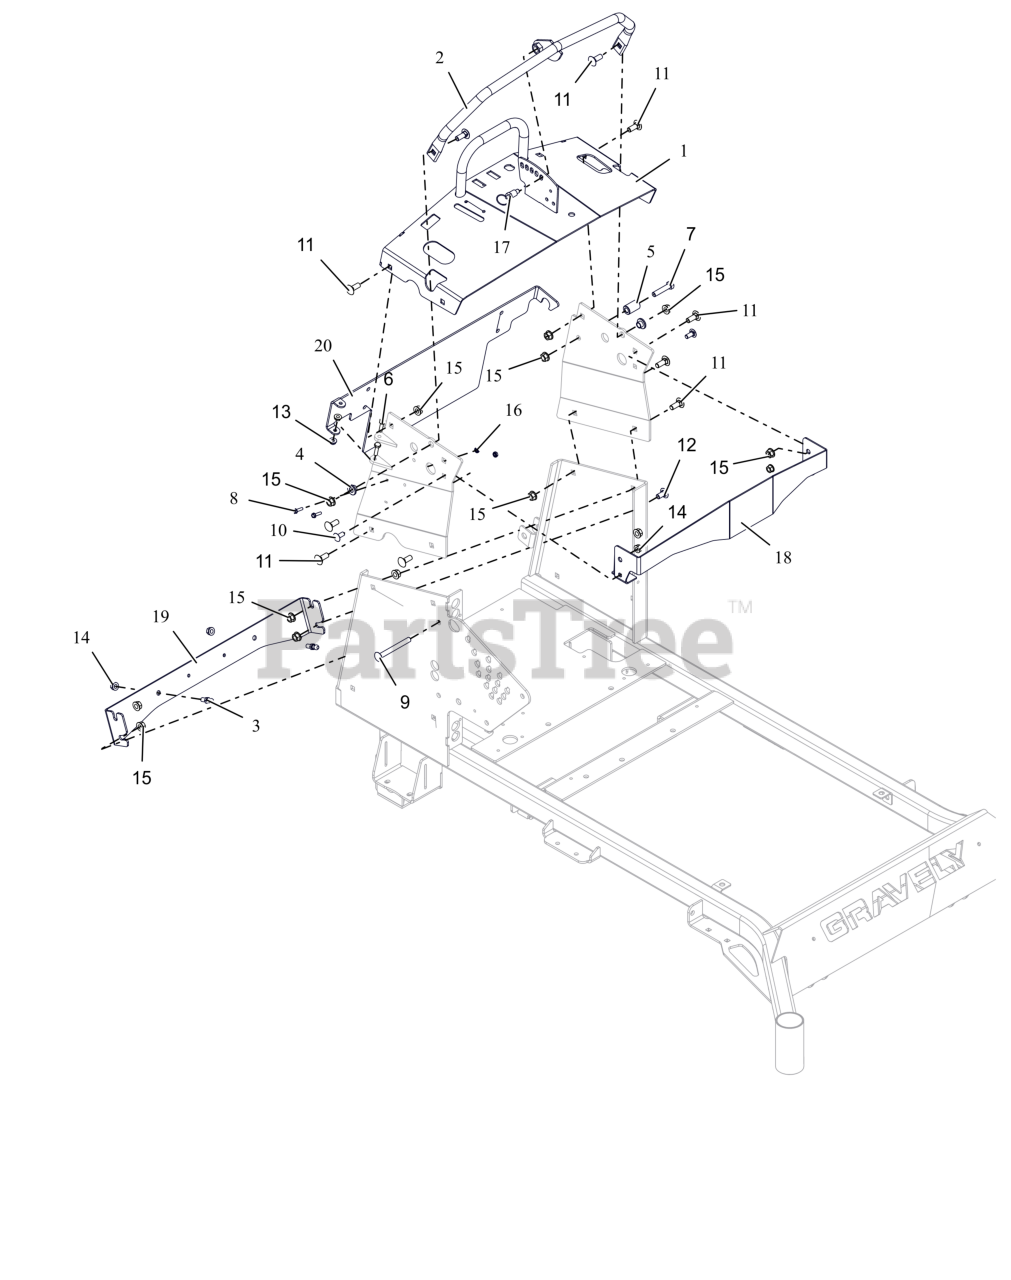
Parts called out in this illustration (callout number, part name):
1	CONSOLE WLDMT W/SAFETY DECALS
2	WLDMT- SPEED CONTROL BAR (BLK)
3	STUD- BALL
4	BSHG-FLG .385X.500X.875X.406
5	BUSHING, SLV .380X.750X1.190
6	BLT,HEX .25-20X1.00 G5 ZCC
7	BLT, HEX .38-16X1.75 G5 ZCC
8	BLT, HWH #10-24X.75 ZCC
9	BLT,RHSSN .38-16X3.50 G5 ZCC
10	BLT, RHSSN.31-18X.750 G5 ZCC
11	BLT, RHSN .38-16X1.00 G5 ZCC
12	BLT, RHSSN .38-16X.75 G5 ZCC
13	NUT-LK-CTR-FLG .25-20 ZC120
14	NUT,LK-CTR-FLG .31-18 GF ZCC
15	NUT-LK-CTR-FLG .375-16 GF ZCC
16	NUT-KEPS 10-24
17	PULL PIN,.50-13THDX.310 PLNGR
18	PLATE- DASH ACCENT (BLACK)
19	BRKT- DAMPER MOUNT (BLACK)
20	OPERATOR PAD MTG BRKT W/SAFETY
